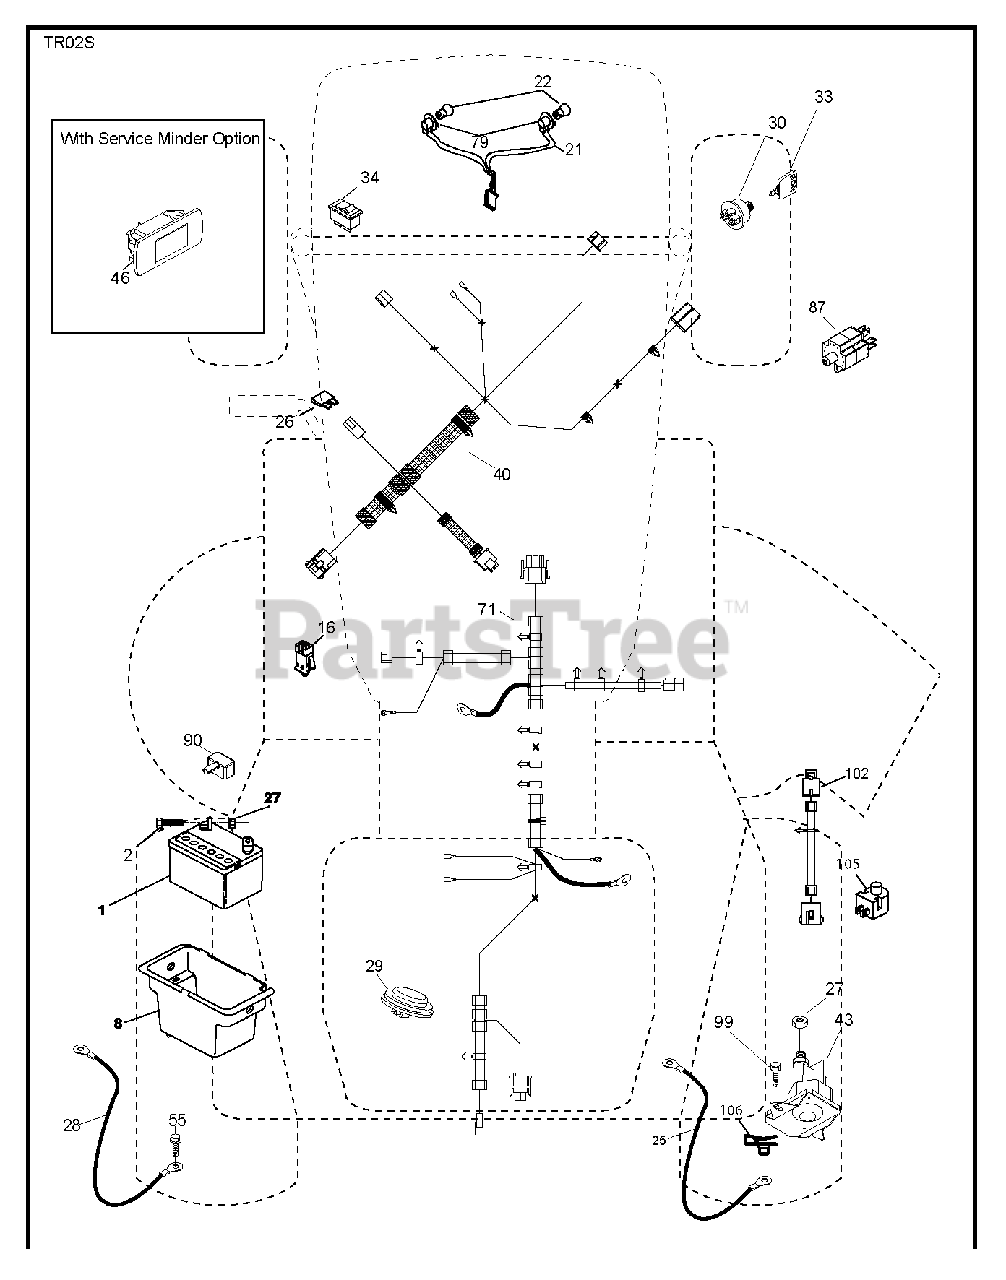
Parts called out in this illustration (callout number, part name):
1	Battery, Dry 30 Amp
2	BOLT.HEX.1/4.X.3/4.DICHROMATE
8	BOX.BATTERY.MNT.REAR.L
16	SWITCH INTERLOOK PUSH-IN
21	HARNESS.LIGHT W/4152J BULBS
25	CABLE.BATT.RED.8GA.17
26	FUSE 20AMP
27	NUT
28	CABLE.GROUND.REAR.BATTERY.8G
29	SWITCH.SEAT.DELTA.OPC.
30	SWITCH.IGN.DELTA.W.LGH.ROS
33	KEY.CHAIN.BLISTER.PACK.GEN.USA
40	HARNESS.TEX.DASH.MAN.REAR BATT
43	SOLENOID.W/BRASS.PLUNGER
46	RP GUAGE.SRVCMNDR.HRMTR.
55	SCREW 5/16"
71	HARNESS.TEX.CHSSIS.REAR.BATT
79	BULB HOLDER ASM.
87	SWITCH.INTRLCK.CLUTCH.
90	COVER.TERMINAL.BATTERY
99	SCREW HEXWSHR 1/4-20X3/4
102	HARNESS PIGTAIL PCH TEX ROS
105	REVERSE SWITCH
106	1/4-20 U NUT
